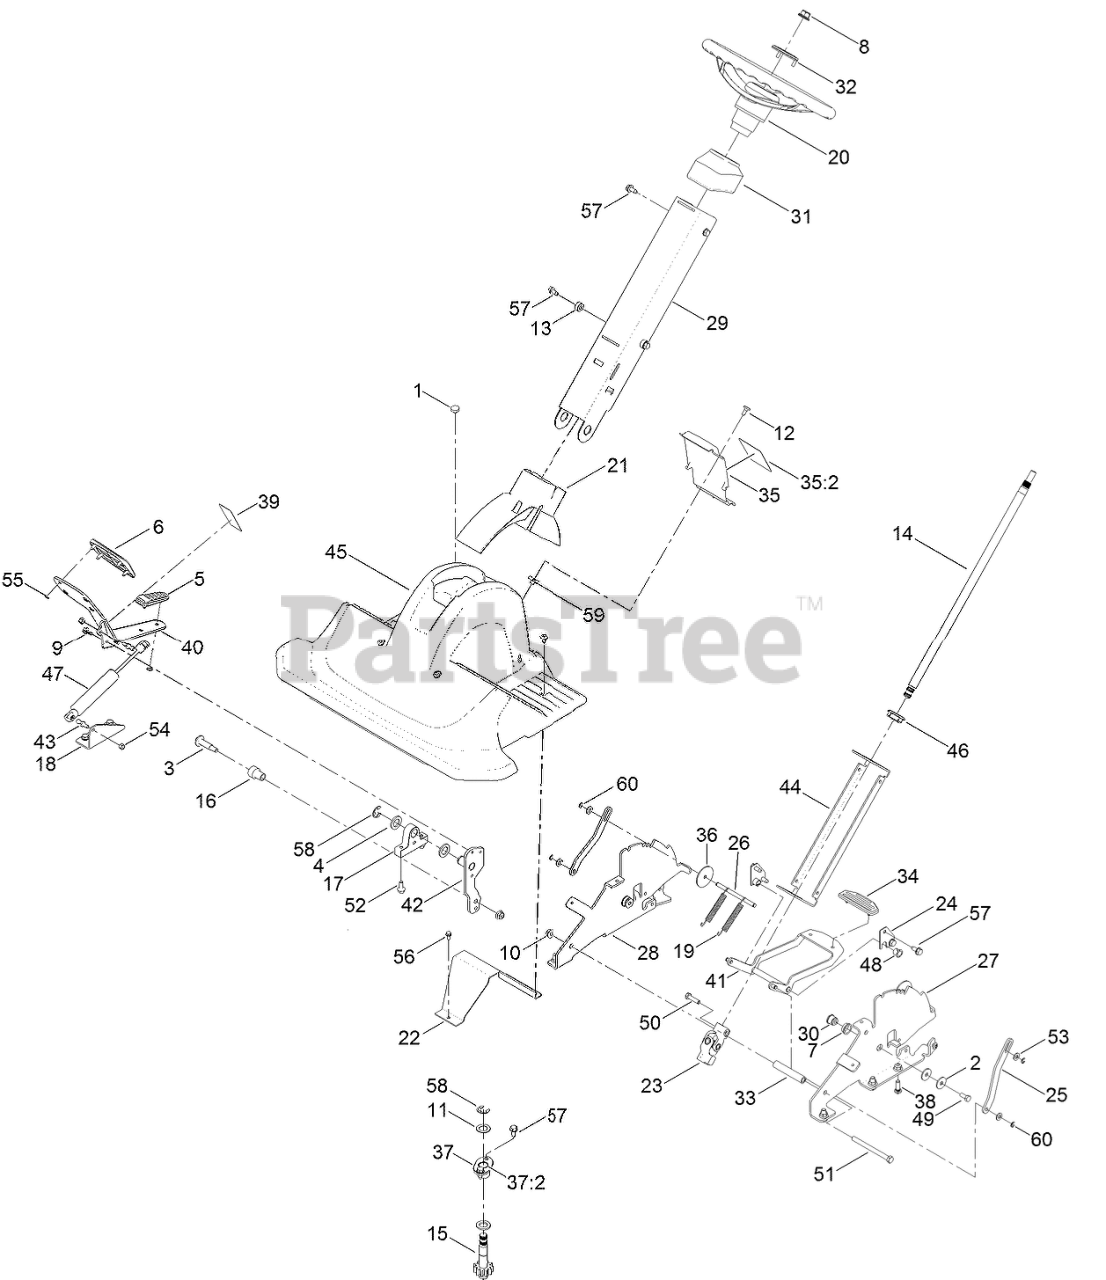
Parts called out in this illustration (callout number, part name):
1	BUMPER
2	WASHER-PIVOT
3	BOLT-WHEEL
4	WASHER
5	PAD-HEEL, HYDRO PEDAL
6	PAD-TOE, HYDRO PEDAL
7	BUSHING-FLANGE
8	NUT-LOCK
9	SCREW-HHF
10	NUT-HF, NI
11	WASHER-THRUST
12	SCREW-SHOULDER
13	SPACER
14	SHAFT-STEERING, UPPER
15	LOWER STEERING SHAFT ASM
16	ROLLER
17	MOUNT-PEDAL PIVOT
18	BRACKET-DAMPER
19	SPRING-EXTENSION
20	WHEEL-STEERING
21	COVER-PIVOT, COLUMN
22	SUPPORT-FOOTREST
23	U-JOINT ASM
24	PLATE-RETAINER
25	PLATE-PLUNGER
26	ROD-PLUNGER
27	BRACKET-PIVOT, COLUMN (LH)
28	BRACKET-PIVOT, COLUMN (RH)
29	COLUMN-FRONT
30	SPACER-PIVOT, COLUMN
31	CAP-COLUMN
32	CAP-WHEEL, STEERING
33	SPACER
34	PAD-TILT PEDAL
35	REAR COVER AND DECAL ASM
35:2	DECAL-DANGER
36	WASHER-SHAFT, TILT
37	FLANGE BEARING ASM
37:2	BUSHING-STRAIGHT
38	STUD-PUSH-IN
39	DECAL-RELEASE, BREAK
40	PEDAL-TRACTION
41	RELEASE PEDAL ASM
42	PIVOT LEVER ASM
43	BALL STUD
44	COLUMN-BACK
45	SHROUD-STYLING, FRONT
46	BEARING-SPHERICAL
47	DAMPER-NON CAVITATING
48	BUSHING-NYLINER
49	SCREW-HH
50	SCREW-HH
51	SCREW-HH
52	SCREW-HHF
53	WASHER-PLAIN
54	NUT-LOCK, NI
55	NUT-PUSH
56	SCREW-HWH
57	SCREW-HWHTF
58	E-RING
60	E-RING
